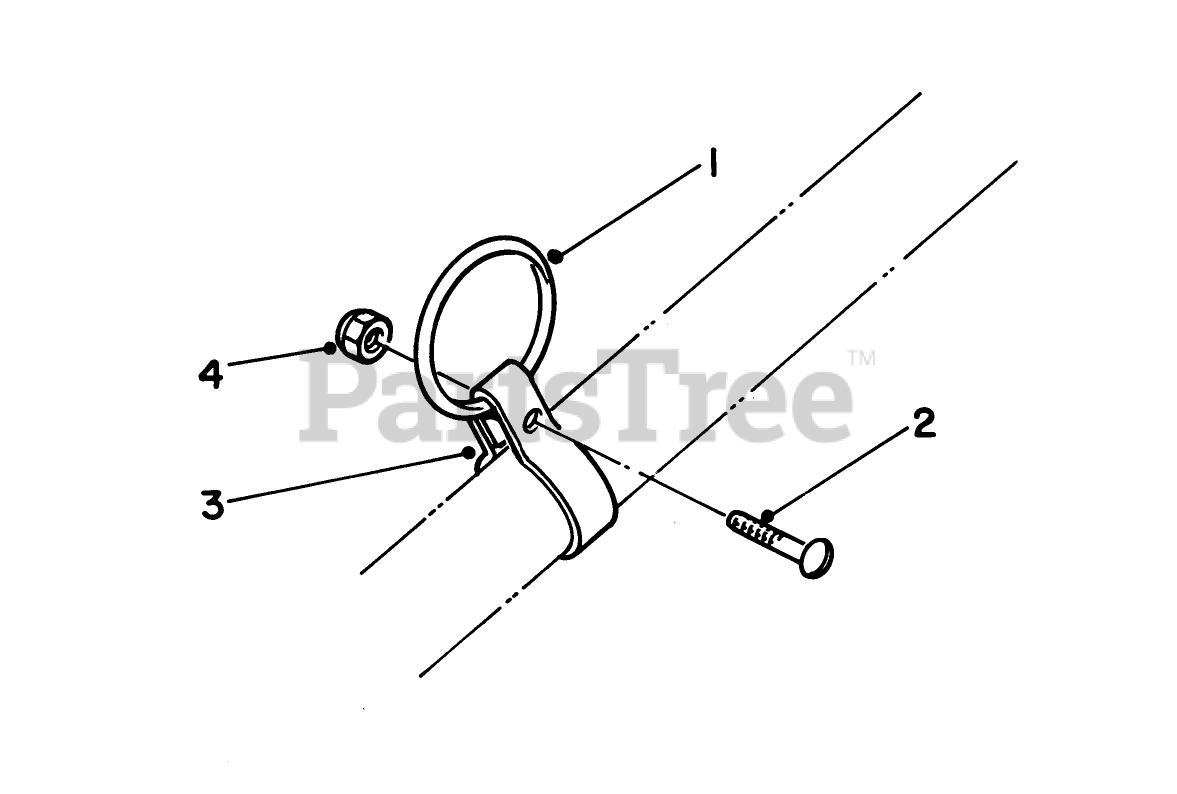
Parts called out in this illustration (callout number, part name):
1	Ring
2	10-24 X 5/8 PAN HD MS
3	Clamp
4	NUT-LOCK, NI
